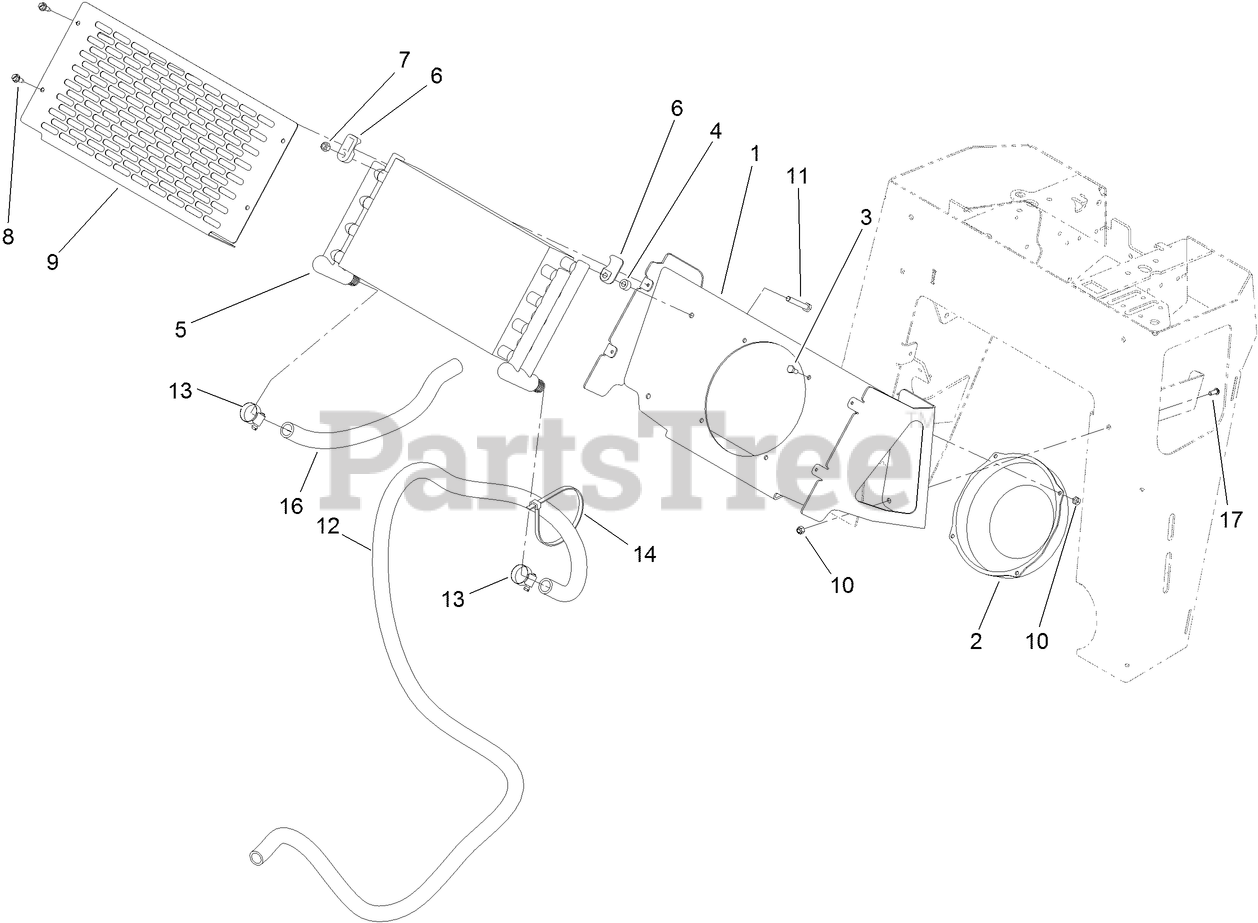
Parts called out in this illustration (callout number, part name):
1	MOUNT-COOLER
3	SCREW-HH
4	SPACER
5	COOLER-OIL
6	CLAMP-COOLER, OIL
7	NUT-LOCK, NI
8	SCREW-HWH
9	COVER-COOLER
10	NUT-LOCK, NI
11	SCREW-HH
12	HOSE-RETURN
13	CLAMP-HOSE
14	TIE-CABLE
16	HOSE-RETURN
17	SCREW-HSBH
